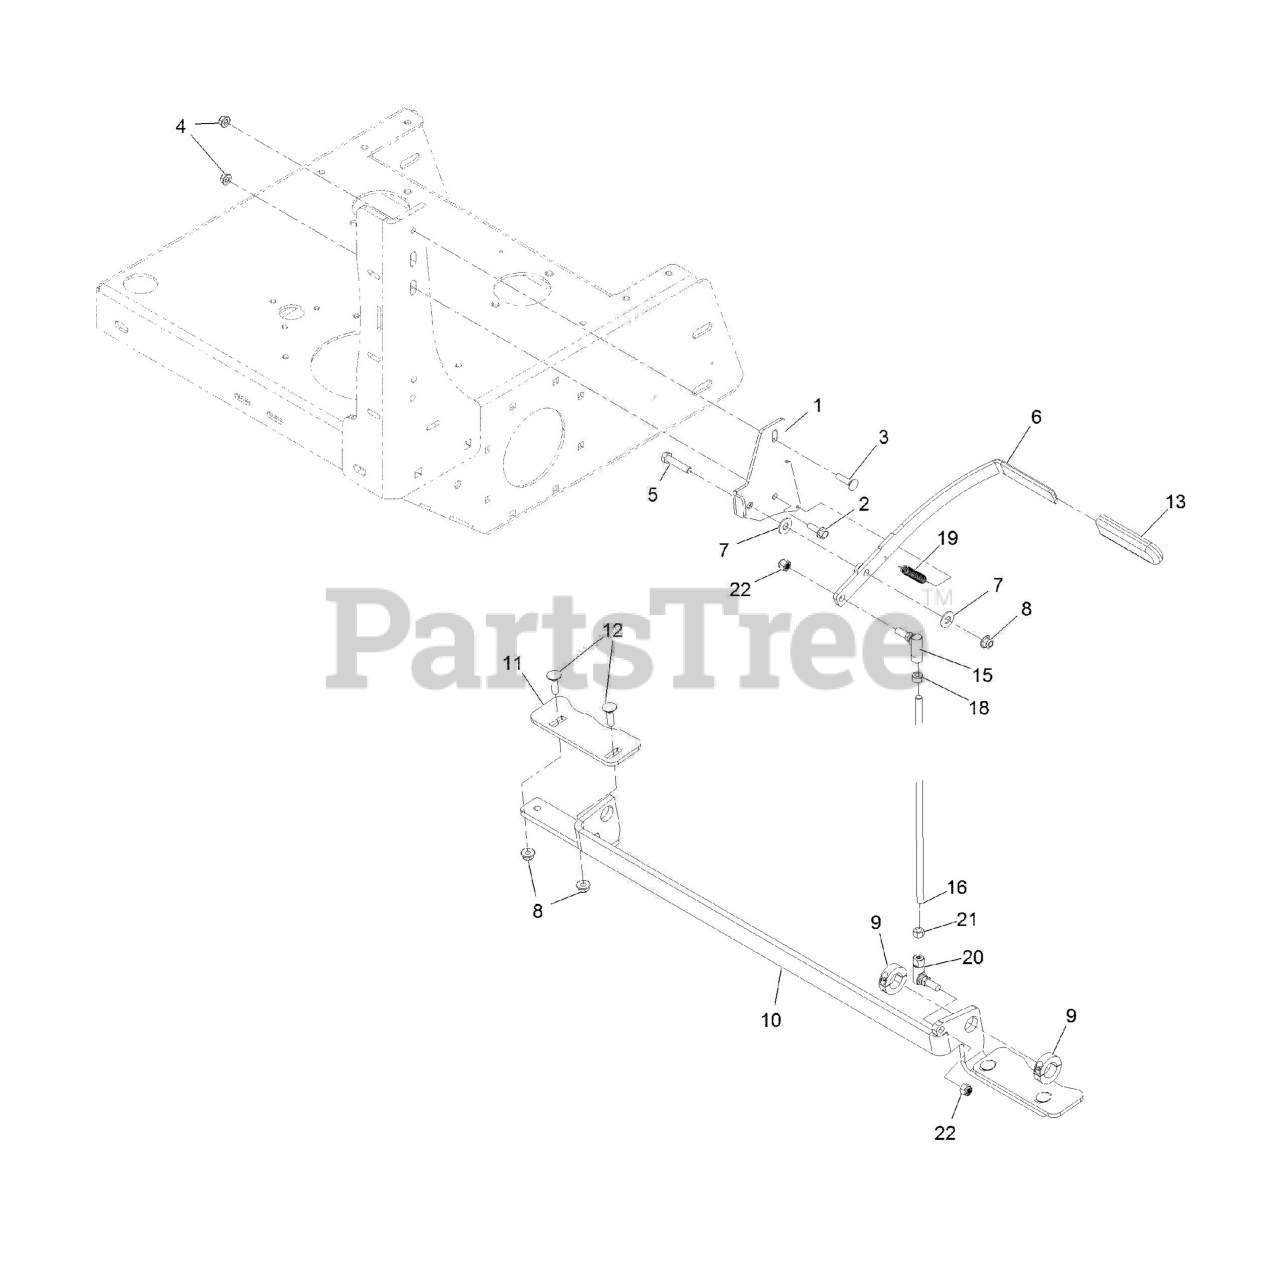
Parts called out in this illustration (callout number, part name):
1	PLATE-BRAKE
2	SCREW-HH
3	Bolt-Carriage 5/16-18 X 1 1/4
4	NUT-HF, NI
5	SCREW-HH
6	HANDLE-BRAKE
7	WASHER-PLAIN
8	NUT-HF, NI
9	COLLAR-LOCKING
10	PIVOT-BRAKE, ROD
11	PAD-BRAKE
12	Bolt-Carriage 3/8-16 X 1 1/4
13	GRIP-LEVER
15	BALL JOINT-SS
16	BRAKE ROD 14.5"
18	NUT-HEX
19	SPRING-EXTENSION
20	BALL JOINT-SS
21	NUT-HEX, LH
22	XREF 126-4803
